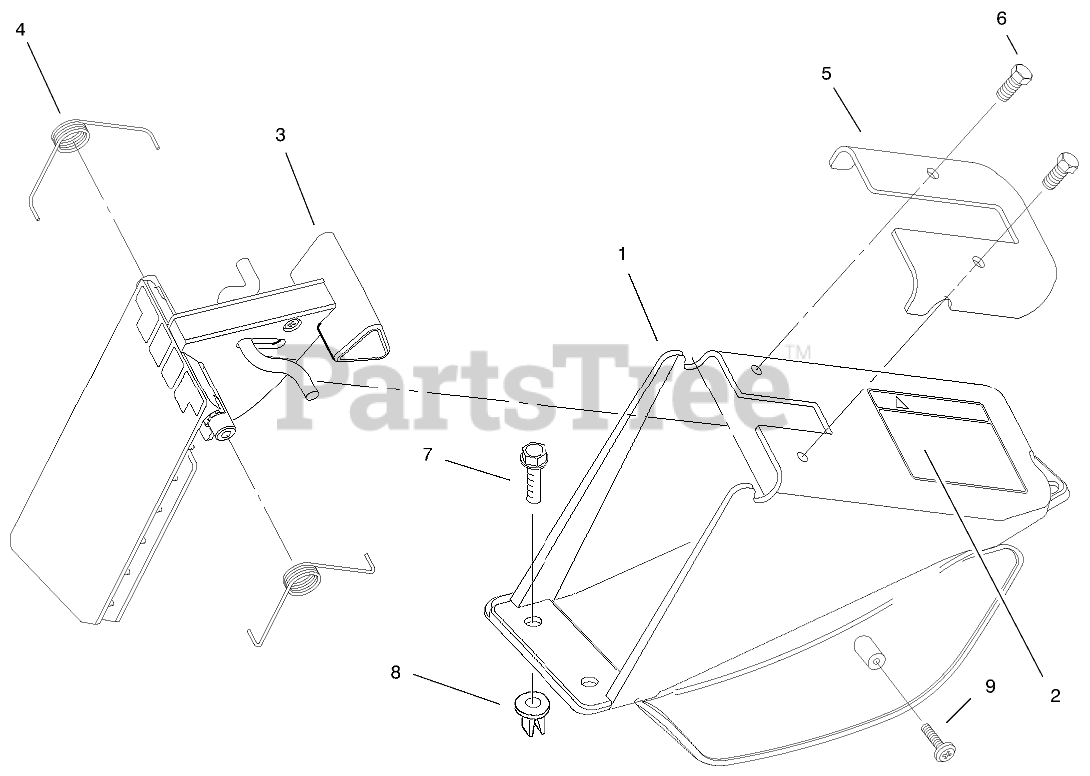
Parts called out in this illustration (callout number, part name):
1	CHUTE - DISCHARGE
2	DECAL - CAUTION DOOR
3	ASM - DISCHARGE DOOR
4	SPRING-DOOR, RH
5	Plate-Discharge
6	SCREW-PLASTITE
7	SCREW-HWH
8	NUT - CLIP
9	SCREW-PPH
